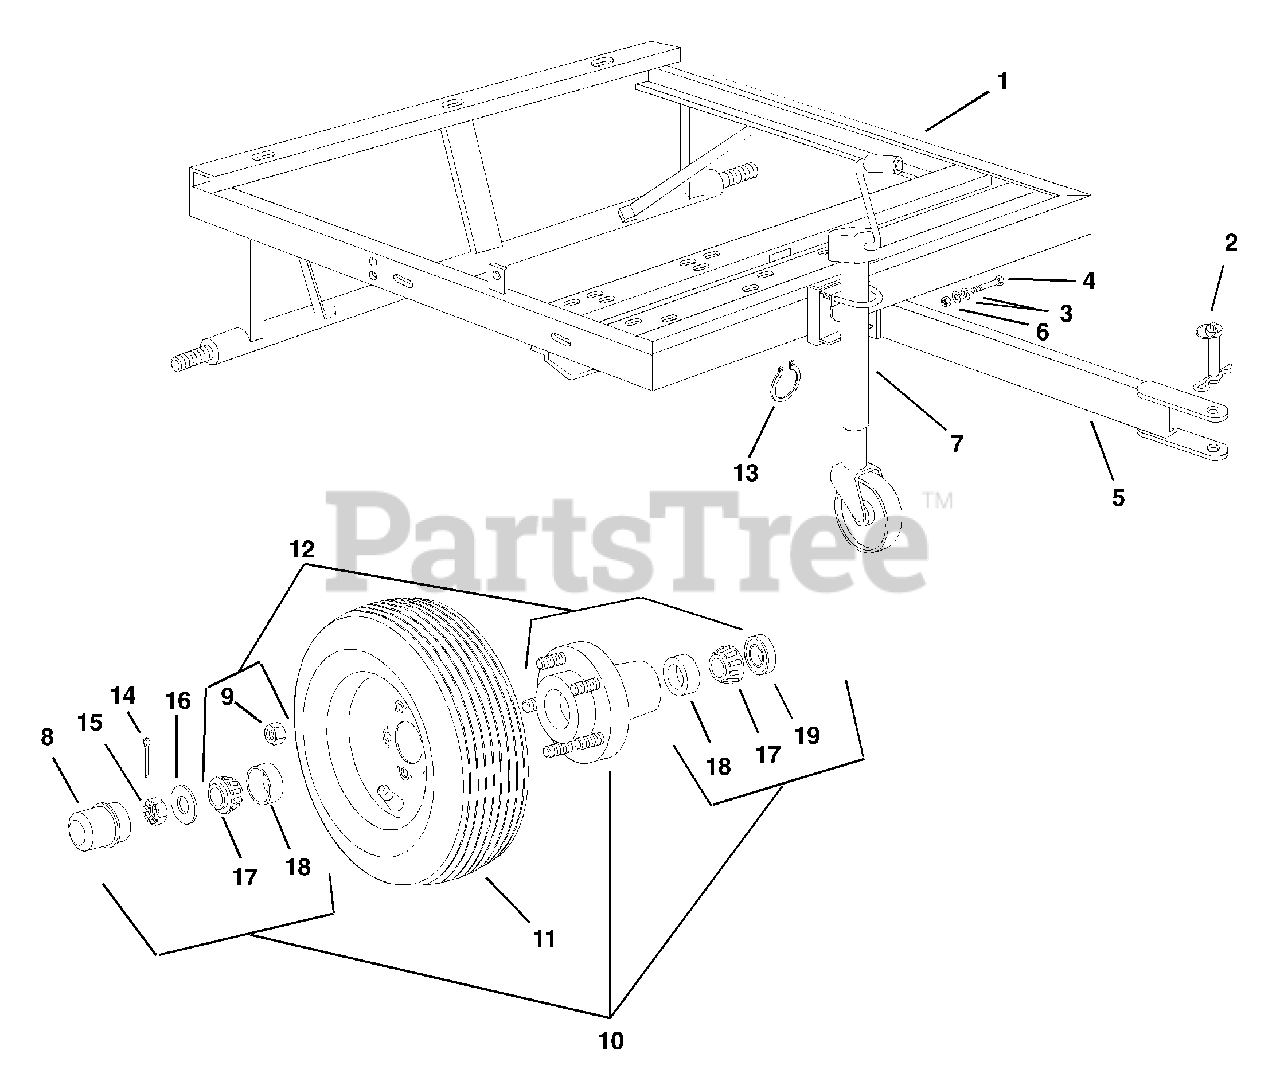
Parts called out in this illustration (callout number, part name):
1	Frame-Trailer Weldment
2	Hitch Pin, 1.00
3	Washer-Flat-Steel .688 x 1.75 x .134
4	Bolt-Hex .62-11 x 3.00 Grade 5
5	Tongue Weldment
6	Nut-Locking-Center .62-11
8	Dust Cap
9	Kit, Wheel Nut
10	Kit, Hub Complete 1050 Vac
11	Tire & Wheel Assembly
12	Hub Assembly
13	Ring-Retaining-External 2.5000 x .078
14	Pin-Cotter .12 x 1.25
15	Nut-Slotted 1.00-14
16	Washer-Flat-Steel 2.00 x 1.12 x .148
17	Cone, Bearing
18	Bearing, Cup
19	Seal
